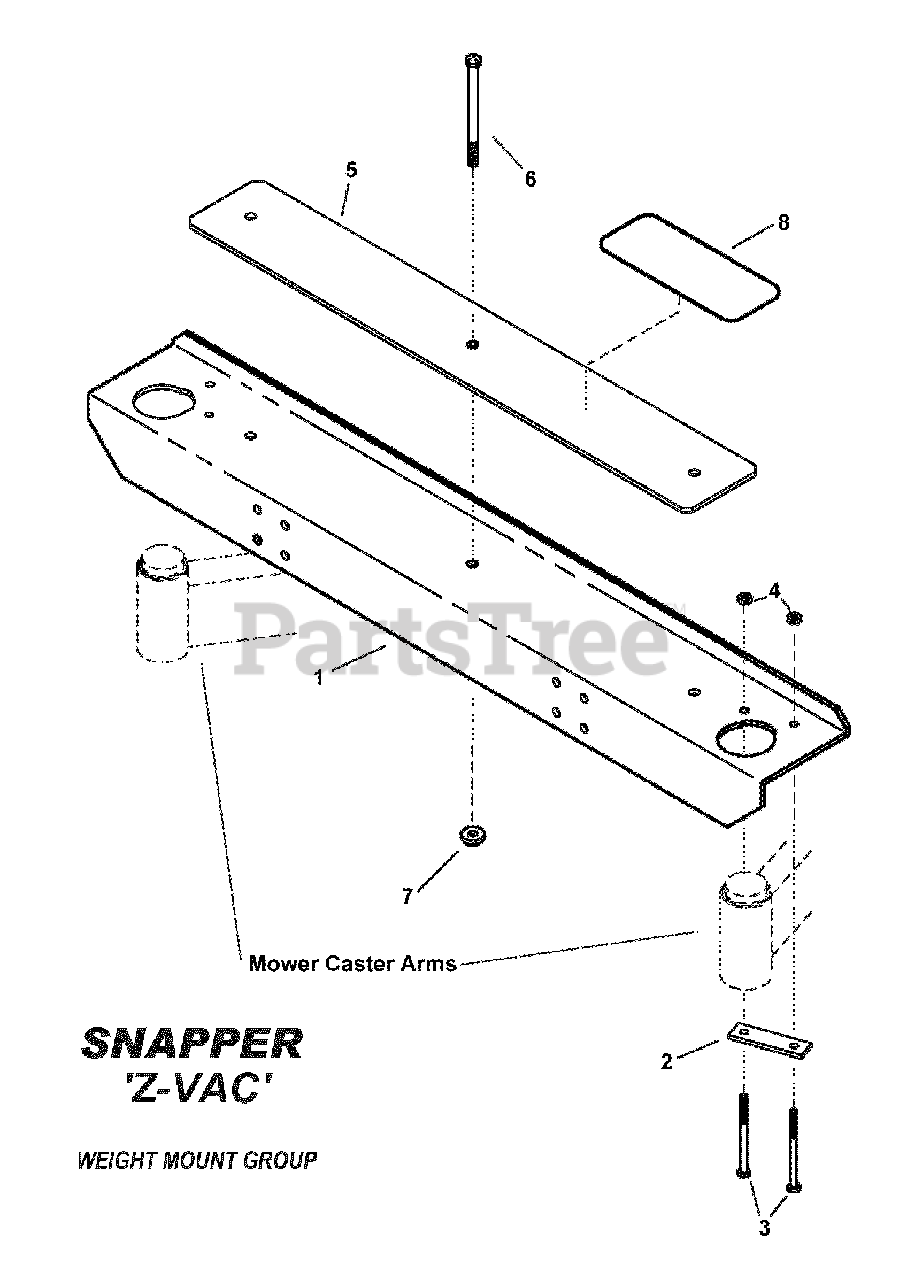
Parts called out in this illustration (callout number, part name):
1	CHANNEL, Weight Mounting
2	BAR, Clamp
3	BOLT, 3/8-16 x 4" Hex Tap, GR5
4	NUT, 3/8-16 Hex Center Lock, GR5 or B
5	BAR, Weight
6	SCREW, 1/2-13 x 4-1/2" Hex Head Cap
7	NUT, 1/2-13 Hex Flange Lock
8	PAD, Anti-Skid, Self-Adhesive
